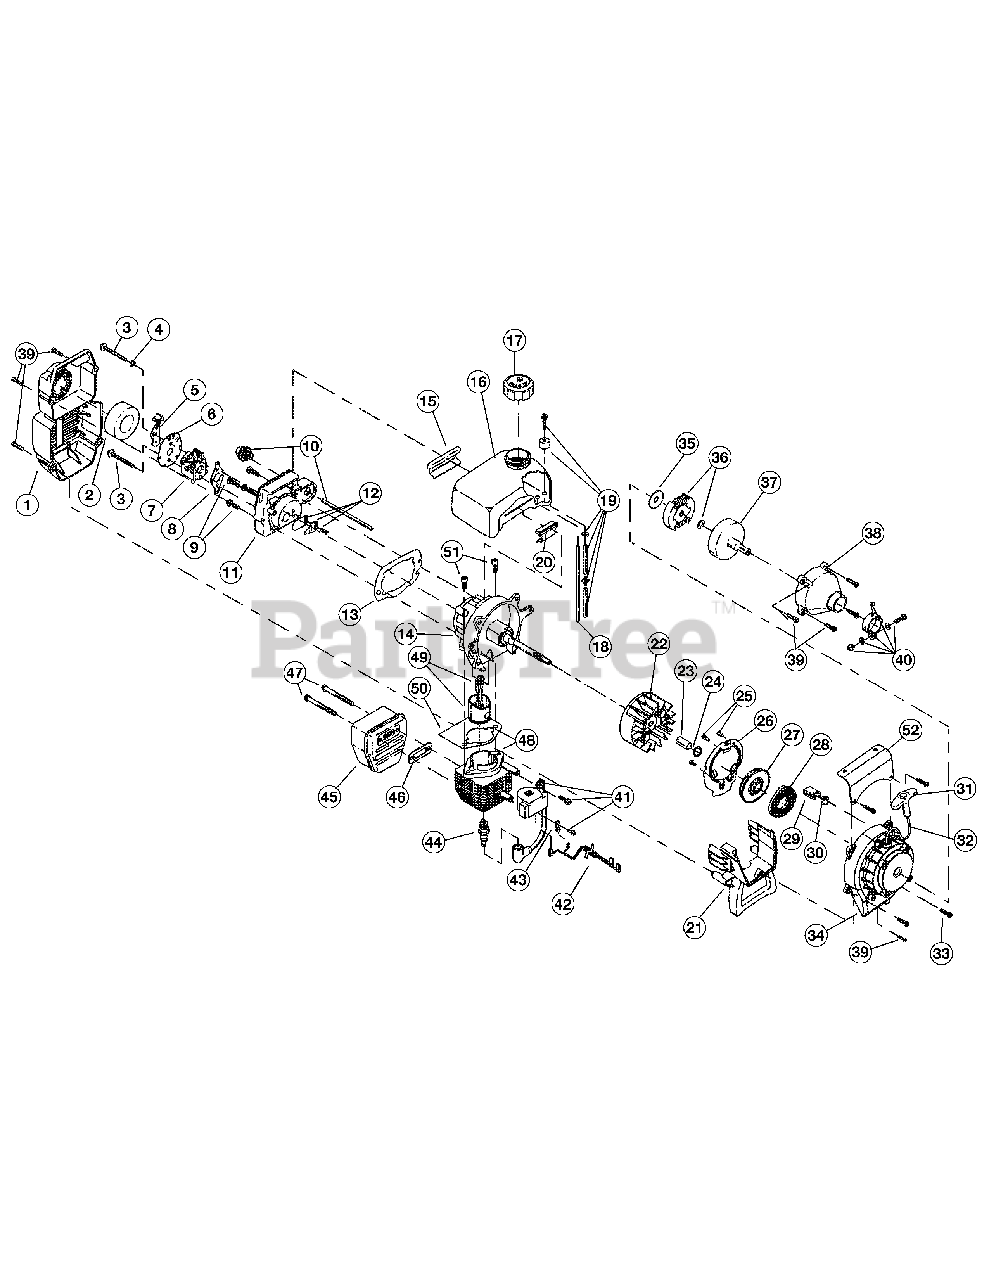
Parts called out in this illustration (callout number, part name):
1	Air Cleaner Assembly (includes 2 & 39)
2	Air Cleaner Filter
3	Carburetor Mounting Screw Assembly
4	Wavey Washer
5	Choke Lever Assembly
6	Choke Plate Assembly (includes 5)
7	Carburetor Assembly (includes 8 & 19)
8	Carburetor Gasket
9	Carb Mount Screw
10	Primer and Hose Assembly
11	Carb Mount Assembly (includes 9, 12 & 13)
12	Reed Assembly
13	Carburetor Mount Gasket
14	Crank Case Service Assembly (includes 9)
15	Rear Mounting Pad
16	Fuel Tank Assembly (includes 17-19)
17	Fuel Cap Assembly
18	Fuel Return Line
19	Fuel Line Assembly
20	Front Mounting Pad
21	Shroud Extension and Stand (includes 39)
22	Flywheel Assembly
24	Pulley Retainer
25	Plate Screw
26	Pressure Plate (includes 25)
27	Recoil Pulley Assembly (includes 24 & 32)
28	Recoil Spring
29	Eyelet Retainer
30	Rope Guide
31	Pull Handle
33	Housing Screw
34	Starter Housing Assembly (Incl. Items 24-33, 39 & 52)
35	Clutch Washer
36	Clutch Rotor Assembly
37	Clutch Drum Assembly
38	Clutch Cover Assembly (includes 39)
39	Clutch Cover Screw
40	Upper Clamp Assembly
41	Module Assembly (includes 43)
42	Wire Lead
43	Ground Tab
44	Spark Plug
45	Muffler Assembly (includes item 46 & 47)
46	Exhaust Gasket
47	Muffler Mounting Bolt Assembly
48	Cylinder Assembly (includes items 48 & 51)
49	Piston & Rod Assembly
50	Cylinder Gasket
51	Cylinder Bolt
52	Fuel Tank Guard
